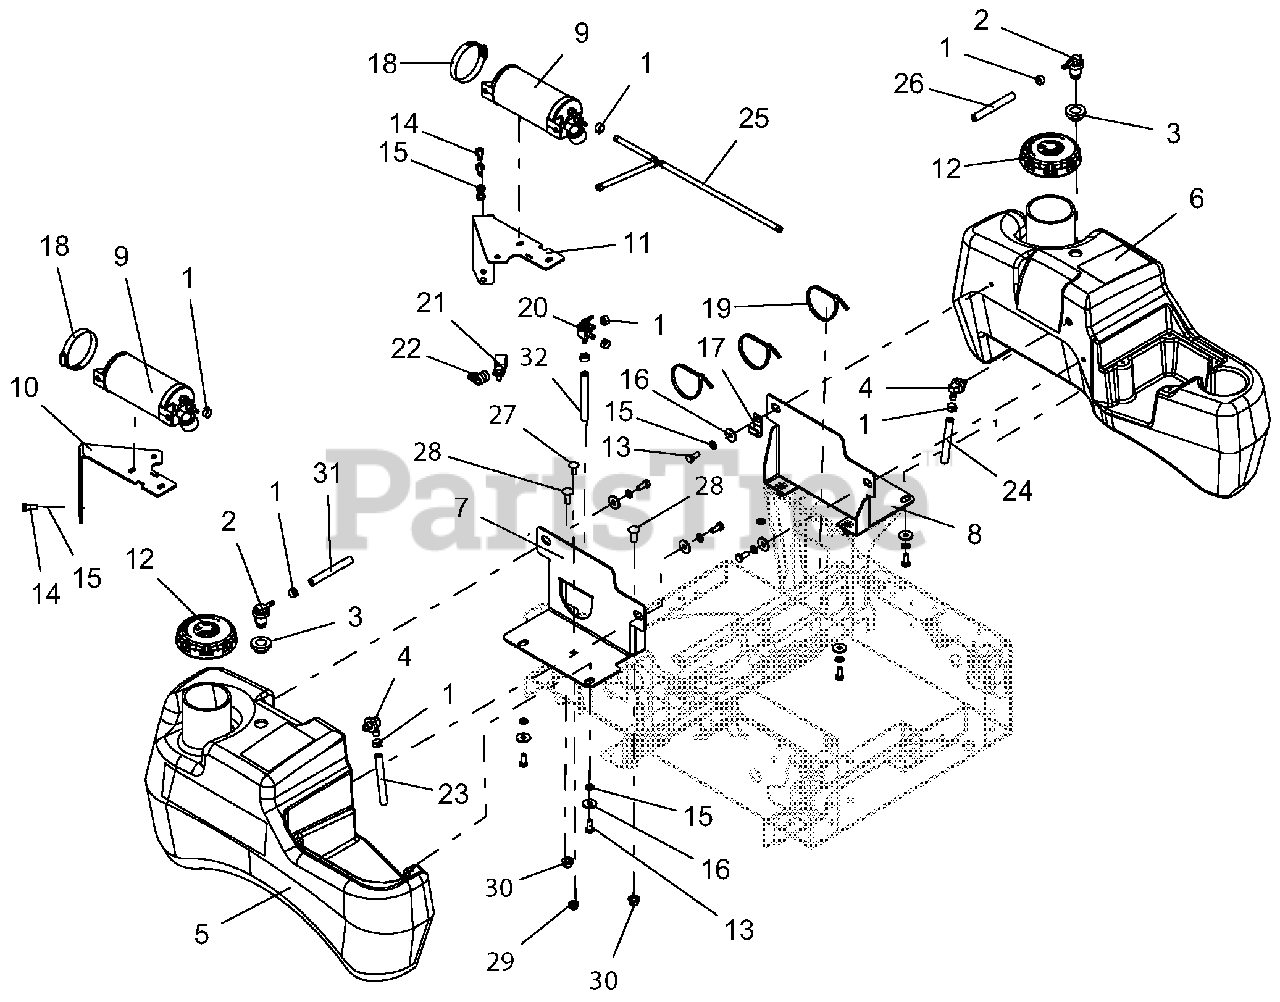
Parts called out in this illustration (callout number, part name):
1	CLAMP, FUEL LINE
2	VALVE, COMBINATION
3	GROMMET, REMOTE VENT NITRILE
4	ASS'Y, SMALL/ MED TANK FUEL PICK-UP
5	TANK, GAS - RH MEDIUM GRAVELY
6	TANK, GAS - LH MEDIUM GRAVELY
7	BRKT, RH MEDIUM FUEL TANK MTG (RED)
8	BRKT, RH MEDIUM FUEL TANK MTG (RED)
9	CANISTER, CARBON 6.3 G CAP.
10	BRKT, MOUNT PT100 RH CARB CANISTER
11	BRKT, MOUNT PT100 RH CARB CANISTER
12	CAP, NON NONVENT AUTOLOCK
13	BLT-HEX .31-18X.75 GR5 YWZC
14	@BLT-HEX M8-1.25X20 YWZC
15	WSHR-LK .31X.078 REG YWZC
16	WSHR-FL-STL .328X1.00X.094 YWZC
17	CLAMP, J
18	CLAMP, HOSE 2.3/3.2
19	CABLE, TIE 5.50 LG
20	VALVE, FUEL
21	CLAMP, CUSHIONED STEEL .75
22	CLAMP, CUSHIONED STEEL
23	.25 LOW-PERM GAS HOSE 18.50" LG - RH TANK TO VALVE
24	.25 LOW-PERM GAS HOSE 40.00" LG - LH TANK TO VALVE
25	ASM, FUEL LINE, PT100 (CARB)
26	.25 LOW-PERM GAS HOSE 21.50" LG - LH TANK VENT TO CARB CANISTER
27	BLT-RDHDSQNK .31-18X.75 G5 YWZC
28	BLT-RDHDSHSQNK.38-16X1.0 G5YZ
29	NUT-LK-NYL-FLG .31-18 YWZC
30	NUT-LK-NYL-FLG .38-16 YWZC
31	.25 LOW-PERM GAS HOSE 25.50" LG - RH TANK VENT TO CARB CANISTER
32	.25 LOW-PERM GAS HOSE 25.00" LG - VALVE TO ENGINE
